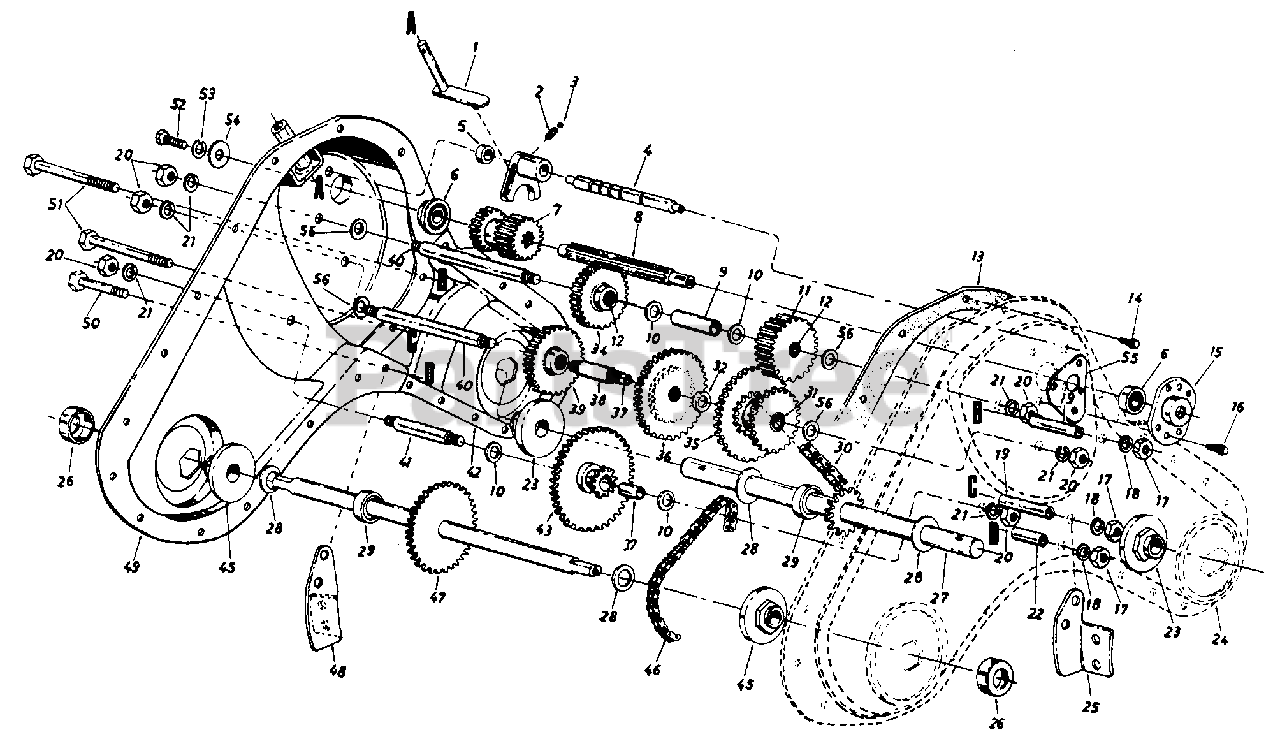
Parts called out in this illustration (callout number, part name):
1	Shifting Bracket Ass'y.
2	Compression Spring .50" Lg.
3	Ball Detent .250" Dia.
4	Detent Shaft 1/2" Dia.
5	Spacer .505" I.D. x .88" O.D.
6	Ball Brg. .62" I.D. x 1.38"
7	Spur Gear 16T (Input)
8	Input Spline Shaft 7/8
9	Spacer .657" I.D. x 2.85" Lg.
10	Fl-Wash. .640" I.D. x 1.24"
11	Spur Gear 30T 7/8" I.D. x1/4" O.D.
12	Needle Bearing 5/8" I.D.
13	Gasket-Trans. Hsg.
14	Hex Wash. S-Tap Scr. 1/4-20 x.50" Lg.
15	1-3/8" Dia. Bearing Housing
16	Hex TT-Tap Scr. 1/4-20 X .75"
17	Hex Nut 5/16-18 Thd.
18	L-Wash. 5/16" I.D.
19	Spacer 1.56" Lg.
20	Hex Nut 7/16-20 Thd.
21	Bell-Wash. .45" I.D. x 1.0"
22	Spacer 1.015" Lg.
23	Tine Shaft Brg. 1.002 x 2.50
24	Trans. Housing Ass'y.-L.H.
27	Tine Shaft Ass'y. 1.00" O.D.
28	Thrust Washer 1.030 I.D. x 1.62" O.D.
29	Spacer 1.0" I.D. x .50" Lg.
30	Chain #50 5/8 Pitch x 52 0 Links-Endless
31	Needle Bearing 5/8" I.D.
32	Fl-Wash. 5/8" I.D. x 1-1/4" O.D. x .150
34	Spur Gear 30T 12/16" I.D. x 1/2" W
35	30/44T Gear Ass'y. Comp.
36	Spur Gear 44T
37	Sleeve Bearing
38	Gear Hub 3/4" I.D. x 3.0" Lg.
39	Spur Gear 30T 1.0" I.D. x 1/2" W
40	Jack Shaft 5/8" Dia. x 5.0"
41	Jack Shaft 5/8" Dia. x 2.38"
42	Trans. Housing Ass'y.-R.H.
43	Spur Gear 55T
45	Wheel Brg. .752 x 2.50
46	#420 Chain 1/2 Pitch x 50 0 Links-Endless
47	Wheel Shaft Ass'y. 13"
51	Hex Bolt 5/16-18 x 2.50"
52	Hex Bolt 1/4-20 x .62" Lg.
53	L-Wash. 3/8" I.D.
54	Fl-Wash. 1/4" I.D. x .93" O.D.
55	Gear Positioner Bracket
56	Fl-Wash. 7/16" I.D. x 1-3/8" O.D.
